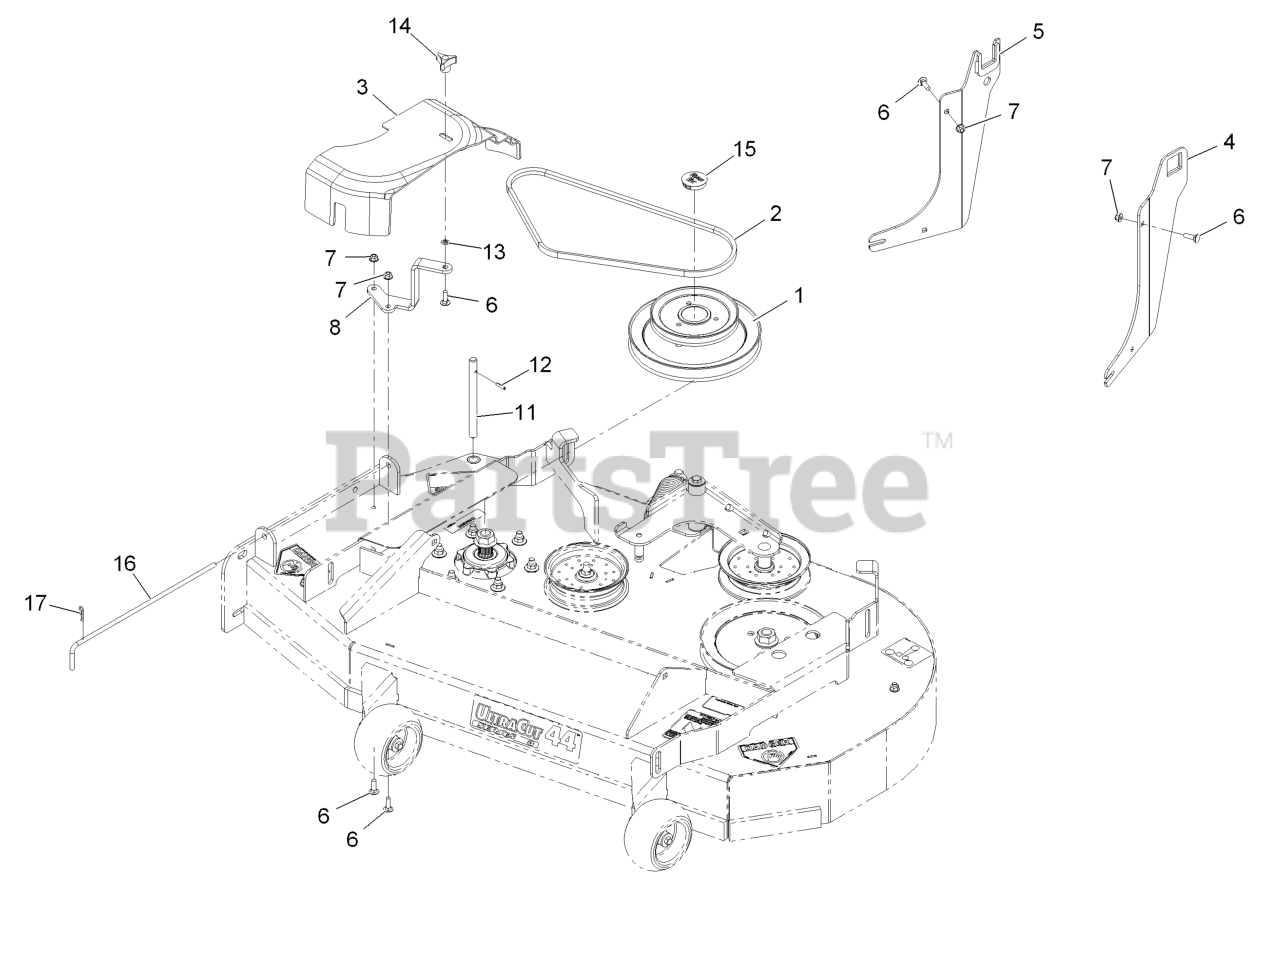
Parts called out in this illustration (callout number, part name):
1	JACKSHAFT-UV DRIVE, 44 SP
2	BELT, BLOWER DRIVE 72
3	COVER-BELT, UV 44
4	BRACKET ASM, LH
5	BRACKET ASM, RH
6	BOLT-CARR
7	NUT-HF, NI
8	BRACKET-BELT COVER 44
11	SHAFT-CATCHER, GRASS
12	PIN-ROLL
13	RING-RETAINING, BOLT
14	KNOB-3 PRONG
15	PLUG, BLACK NYLON 1.75
16	PIN,CHUTE PIVOT
17	PIN-COTTER
